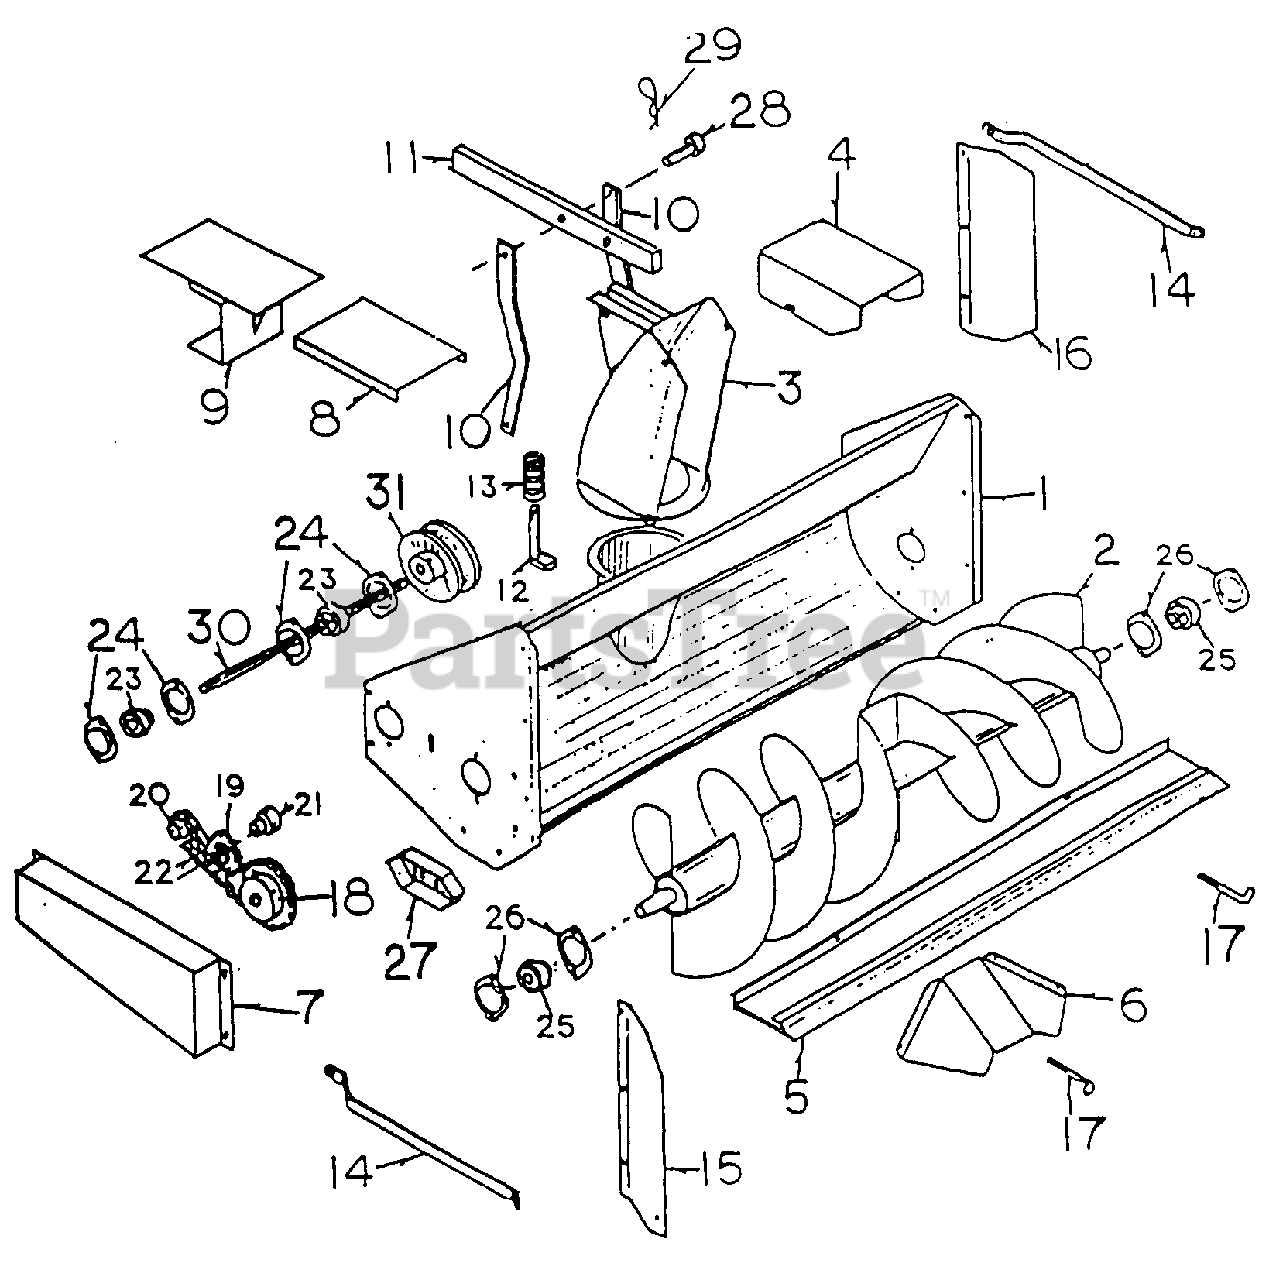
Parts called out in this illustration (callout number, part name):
1	SNOWBLOWER BLADE
2	AUGER
3	CHUTE
4	SNOW DEFLECTOR
5	BLADE
6	SNOW RETAINER
7	CHAIN GUARD
8	BELT GUARD
9	BELT RETAINER
10	CHUTE LOCK LINKAGE
11	HANDLE
12	CHUTE LOCK
13	CHUTE LOCK SPRING
14	EXTENDER BRACES
15	R.H. EXTNDER
16	L.H. EXTNDER
17	BLADE BOLT
18	AUGER SPROCKET
19	IDLER SPROCKET
20	DRIVE SPROCXET
21	IDLER SPROCKET BUSHINS
22	CHAlN
23	3/4 BERING
24	3/4 BERING FLANGE
25	1 In. BEARING
26	1 In. BEARING FLANGE
27	SKID SHOSS
28	PIN
29	HAIR PIN
30	SHAFT
31	PULLEY
